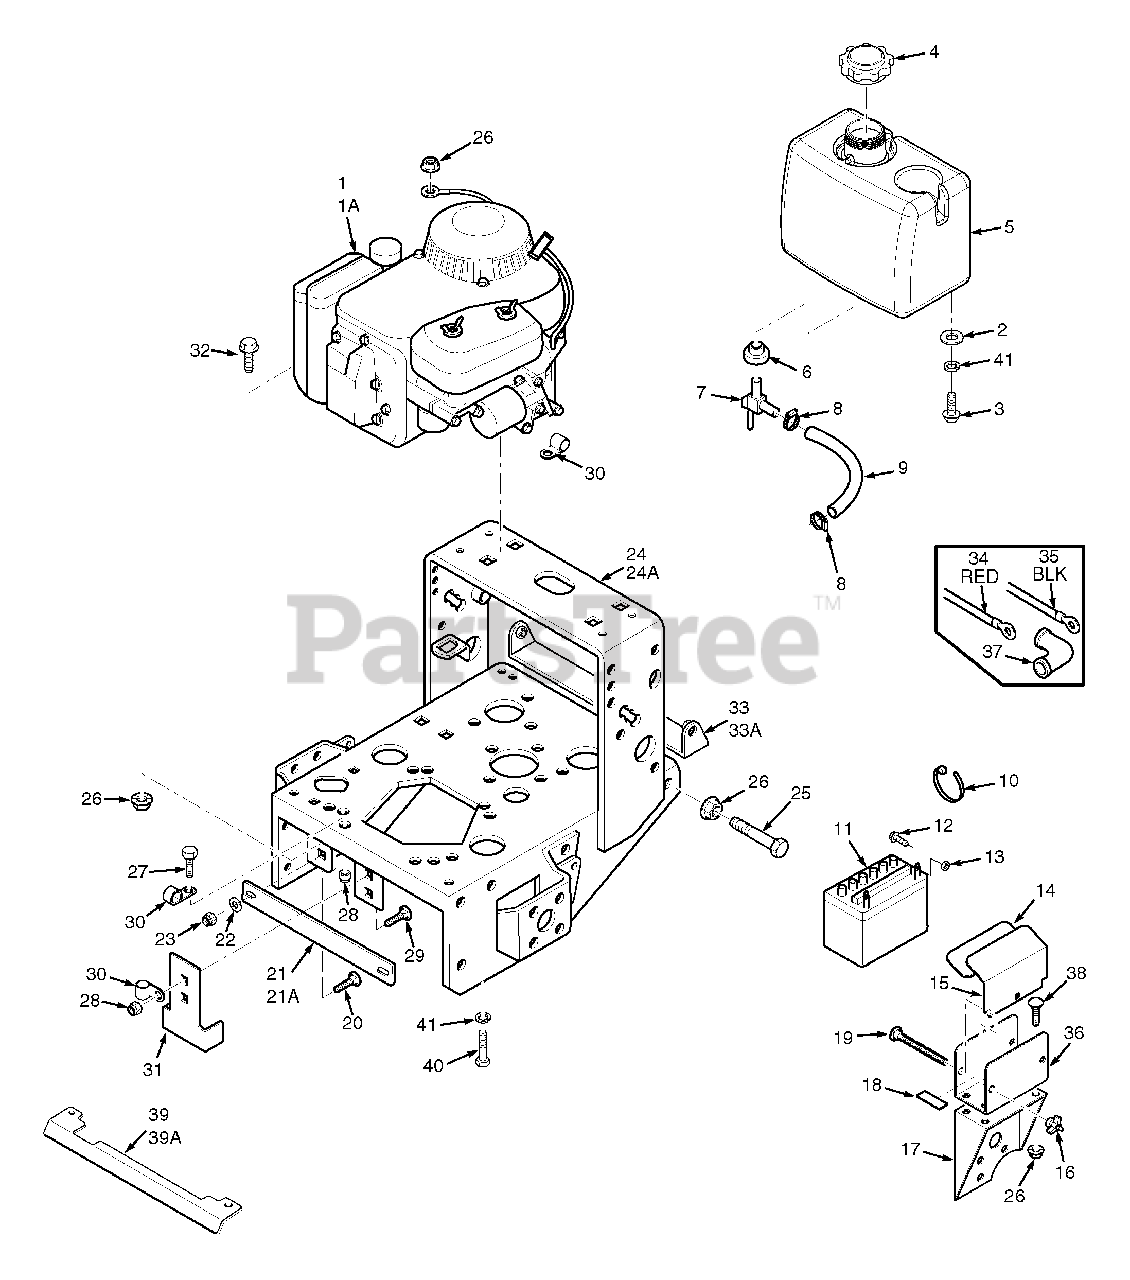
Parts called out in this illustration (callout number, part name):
1	Engine, 17KAE Kawasaki
1A	Engine, 21KAE Kawasaki
2	Flatwasher, 5/16 (.375 x 875 x .083)
3	Capscrew, 5/16-18 x 1" Hex Head
4	Cap, Fuel Tank
5	Fuel Tank Assy.
6	Bushing
7	Valve, Fuel Shut-off
8	Clamp, Fuel Hose
9	Fuel Hose, 1/4 ID x 20"
10	Cable Tie
11	Battery
12	Bolt, 1/4-20 x .50"
13	Nut, 1/4-20
15	Battery Cover
16	Wing Nut, 1/4-20
17	Battery Support
18	Pad, Rubber
19	Bolt, 1/4-20 x 6" Carriage
20	Carriage Bolt, 3/8-16 X 1-1/4"
21	Brace, (16" Small Frame)
21A	Brace, (20" Large Frame)
22	Flat Washer .391 x .938 x .105
23	Nut, 3/8-16 Elastic Stop
24	Engine Deck, 16" Wide, w/decals
24A	Engine Deck, 20" Wide, w/decals
25	Bolt, 5/16-18 x 2" Hex Head
26	Nut, 5/16-18 Serr. Flange
27	Hex Head Bolt, 5/16-18 x .75"
28	Nut, 5/16-18 Elastic Stop
29	Carriage Bolt, 5/16-18 x 1"
31	Clutch Bracket
32	Cap Scrw, 5/16-18 x 1.50" Sr. Flg.
33	Pulley Guard, 16" Frame
33A	Pulley Guard, 20" Frame
34	Battery Cable, 31.5" Red
35	Battery Cable, 31.5" Black
36	Battery Box
37	Rubber Boot
38	Carriage Bolt, 5/16-18 x .75"
39	Heatshield (16" Small Frame)
39A	Heatshield (20" Large Frame)
40	Bolt, 5/16-18 x 1" Sr. Flg. Hex Head
41	Lock Washer 5/16"
